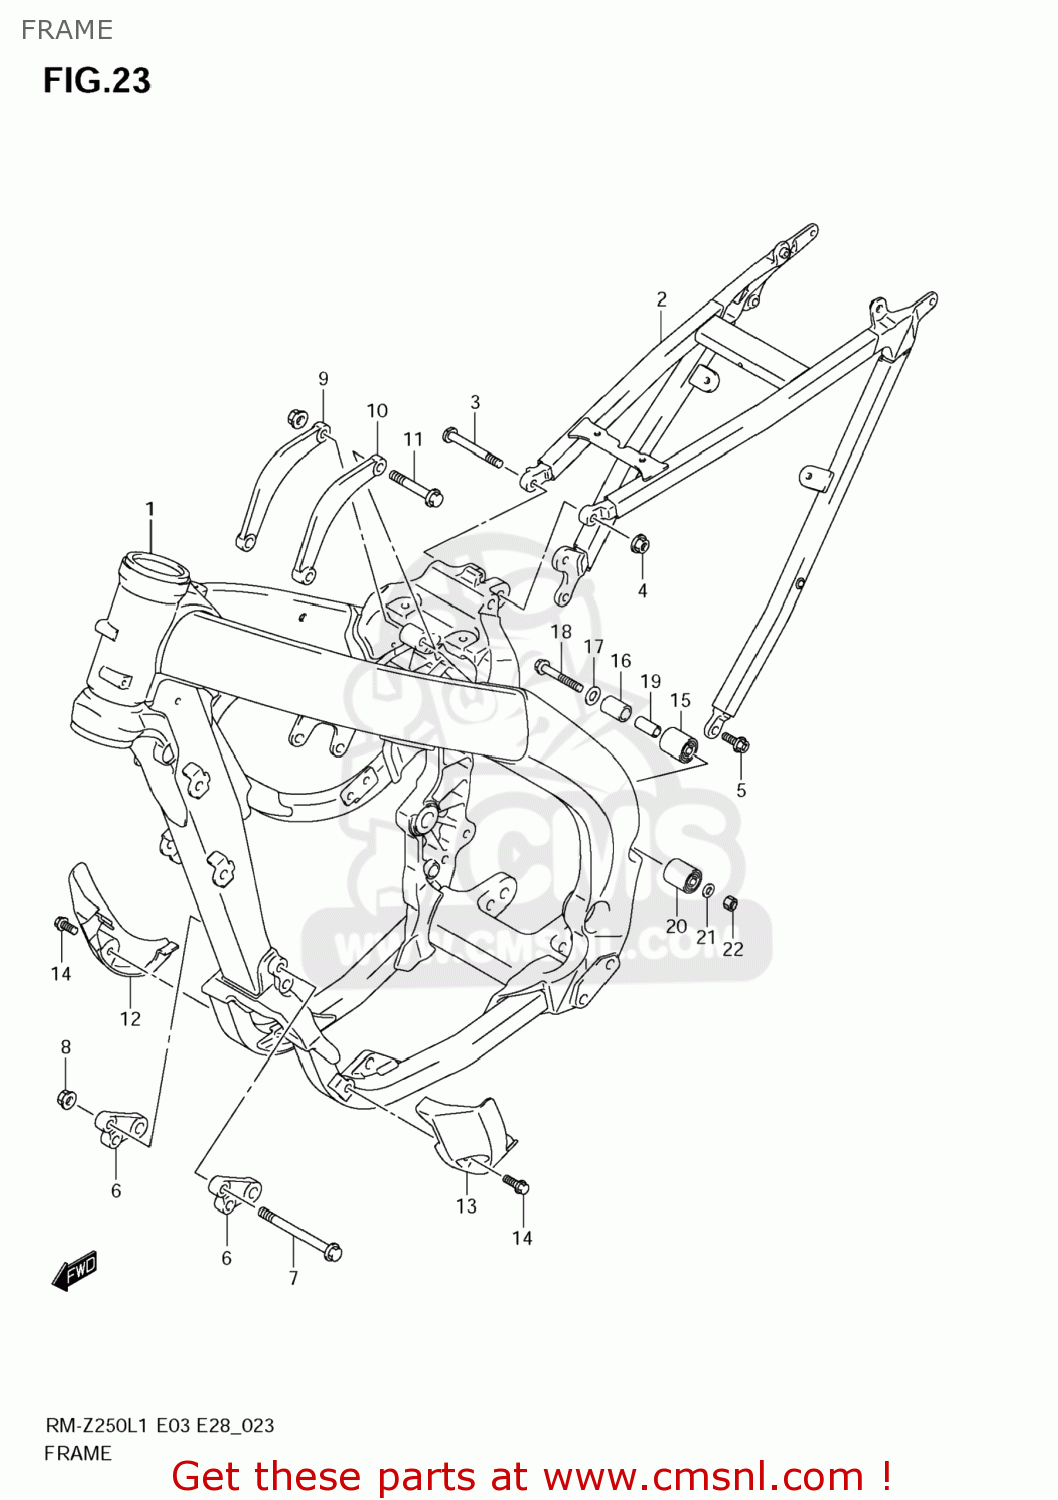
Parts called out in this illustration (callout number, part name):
1	FRAME
2	RAIL,SEAT
3	BOLT,SEAT RAIL UPR
4	NUT
5	BOLT(8X20)
6	BRACKET,ENGINE MOUNTING FR
7	BOLT(8X95)
8	NUT
9	BRACKET,ENGINE MOUNTING UPR,R
10	BRACKET,ENGINE MOUNTING UPR,L
11	BOLT(8X55)
12	PROTECTOR,FR,R
13	PROTECTOR,FR,L
14	BOLT(6X16)
15	ROLLER,CHAIN
16	COLLAR,CHAIN ROLLER
17	WASHER(8.5X23X1.5)
18	BOLT(8X45)
19	SPACER(8.6X12.2X25.5)
20	ROLLER,CHAIN
21	SHIM(8X12X1)
22	NUT
